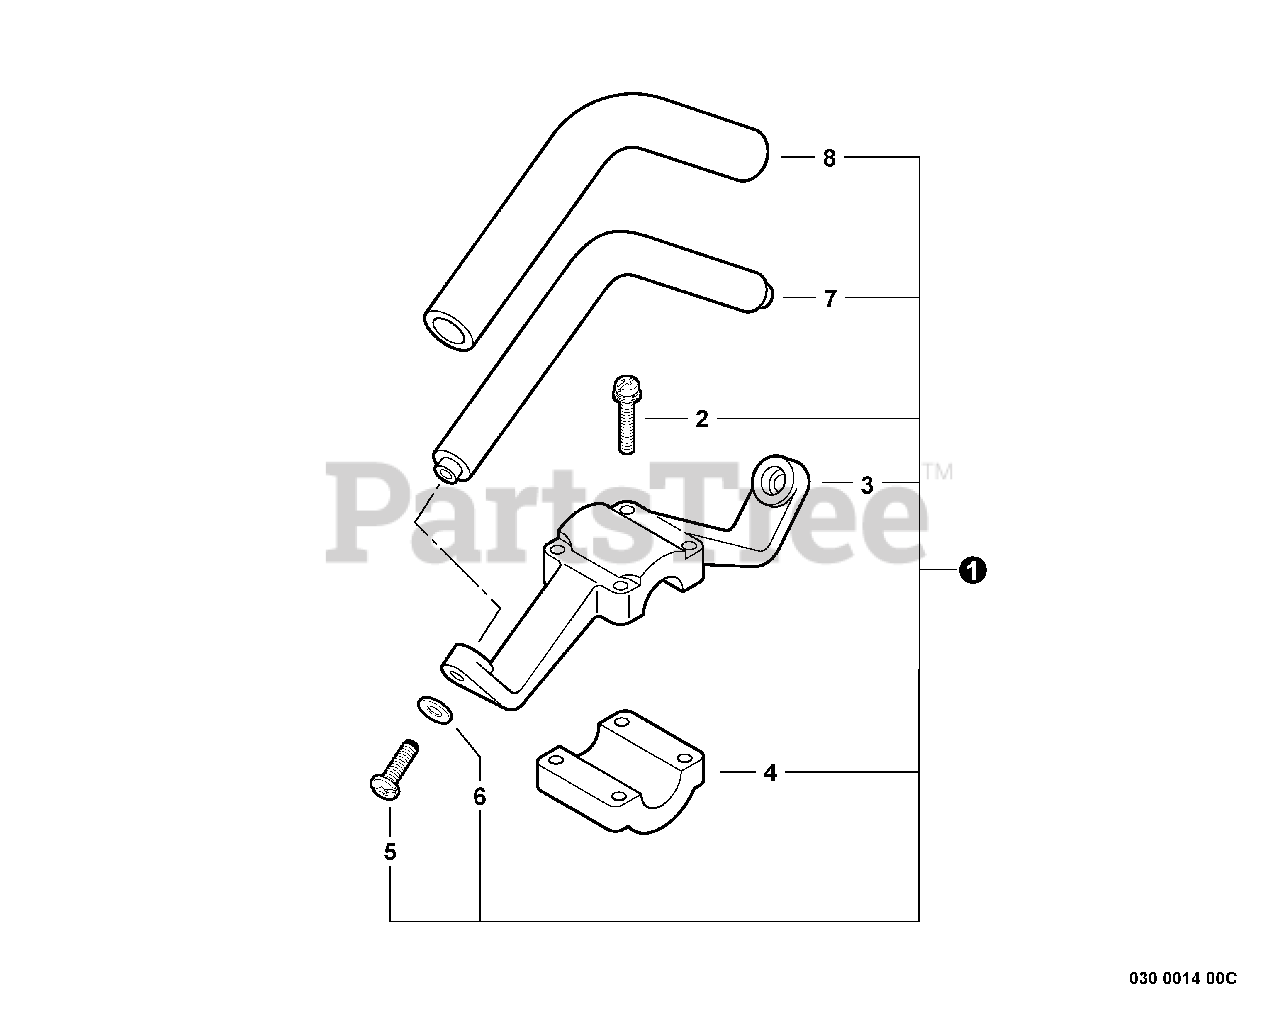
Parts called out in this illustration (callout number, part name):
1	HANDLE ASSY, SUPPORT
2	SCREW 5×35
3	BRACKET, HANDLE
4	BRACKET, HANDLE
5	SCREW, TAPPING 5×20
6	WASHER, FLAT 5.5×10×0.8
7	HANDLE, SUPPORT
8	GRIP, HANDLE
